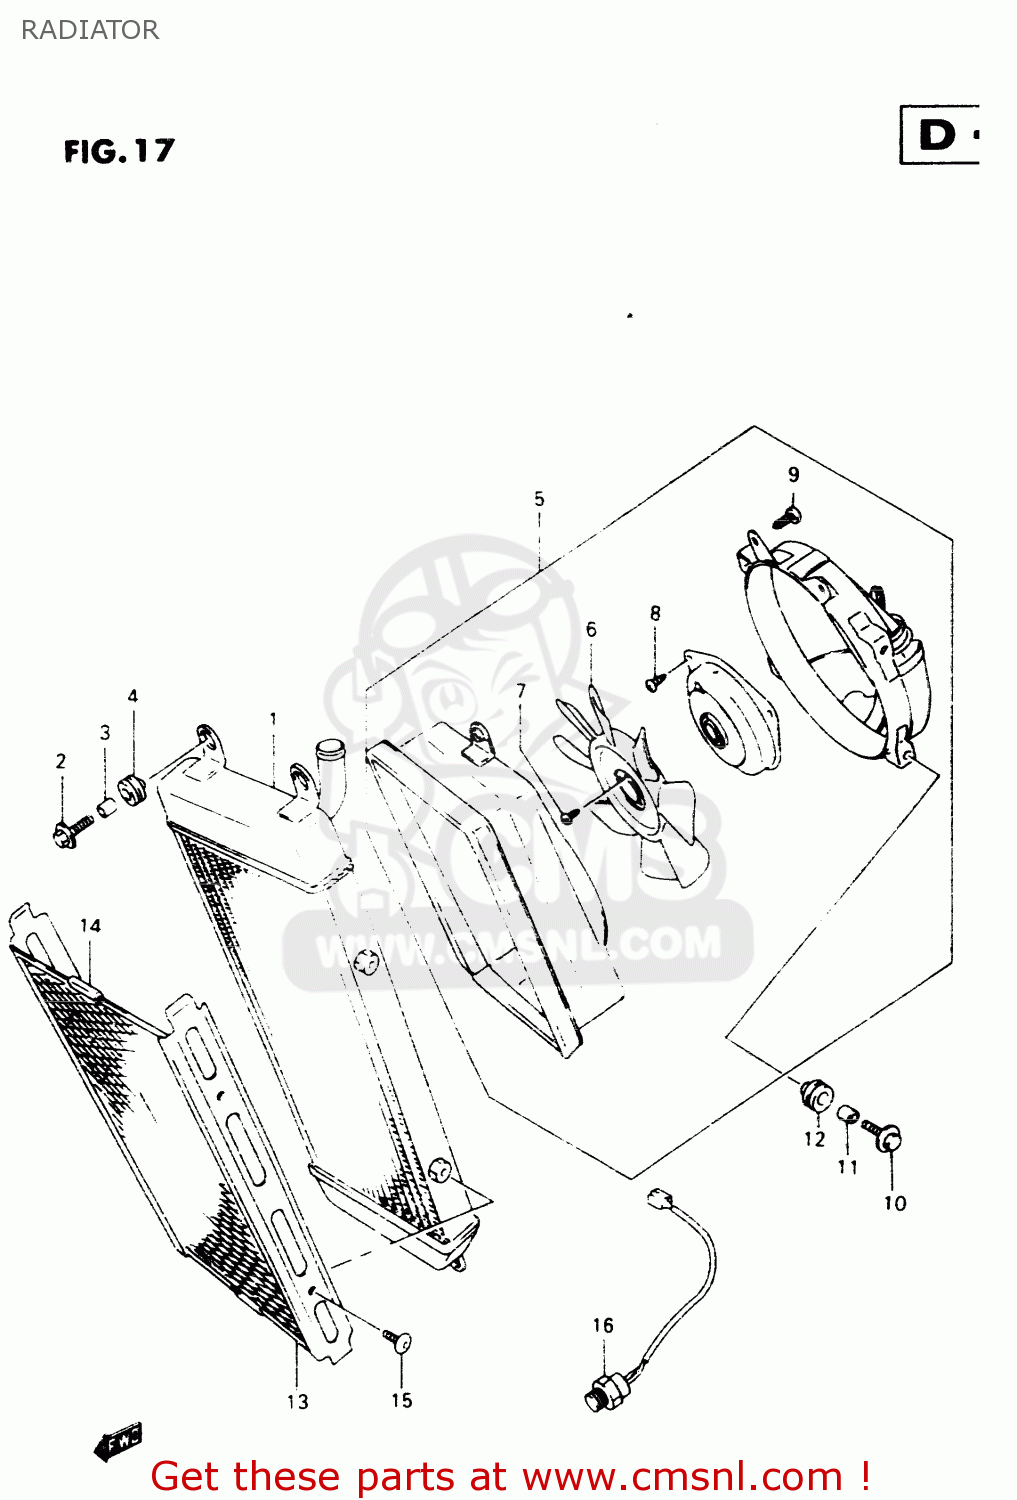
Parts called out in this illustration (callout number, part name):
1	RADIATOR ASSY,WATER
2	BOLT 6X20
3	SPACER(6.5X10X10)
4	CUSHION
5	FAN ASSY,RADIATOR
6	FAN
7	SCREW 4X6
8	SCREW
9	SCREW 5X12
10	BOLT 6X20
11	SPACER(6.5X10X10)
12	CUSHION
13	COVER,RADIATOR
14	PROTECTOR,CTR
15	SCREW(6X10)
16	SWITCH ASSY,WATER TEMP
